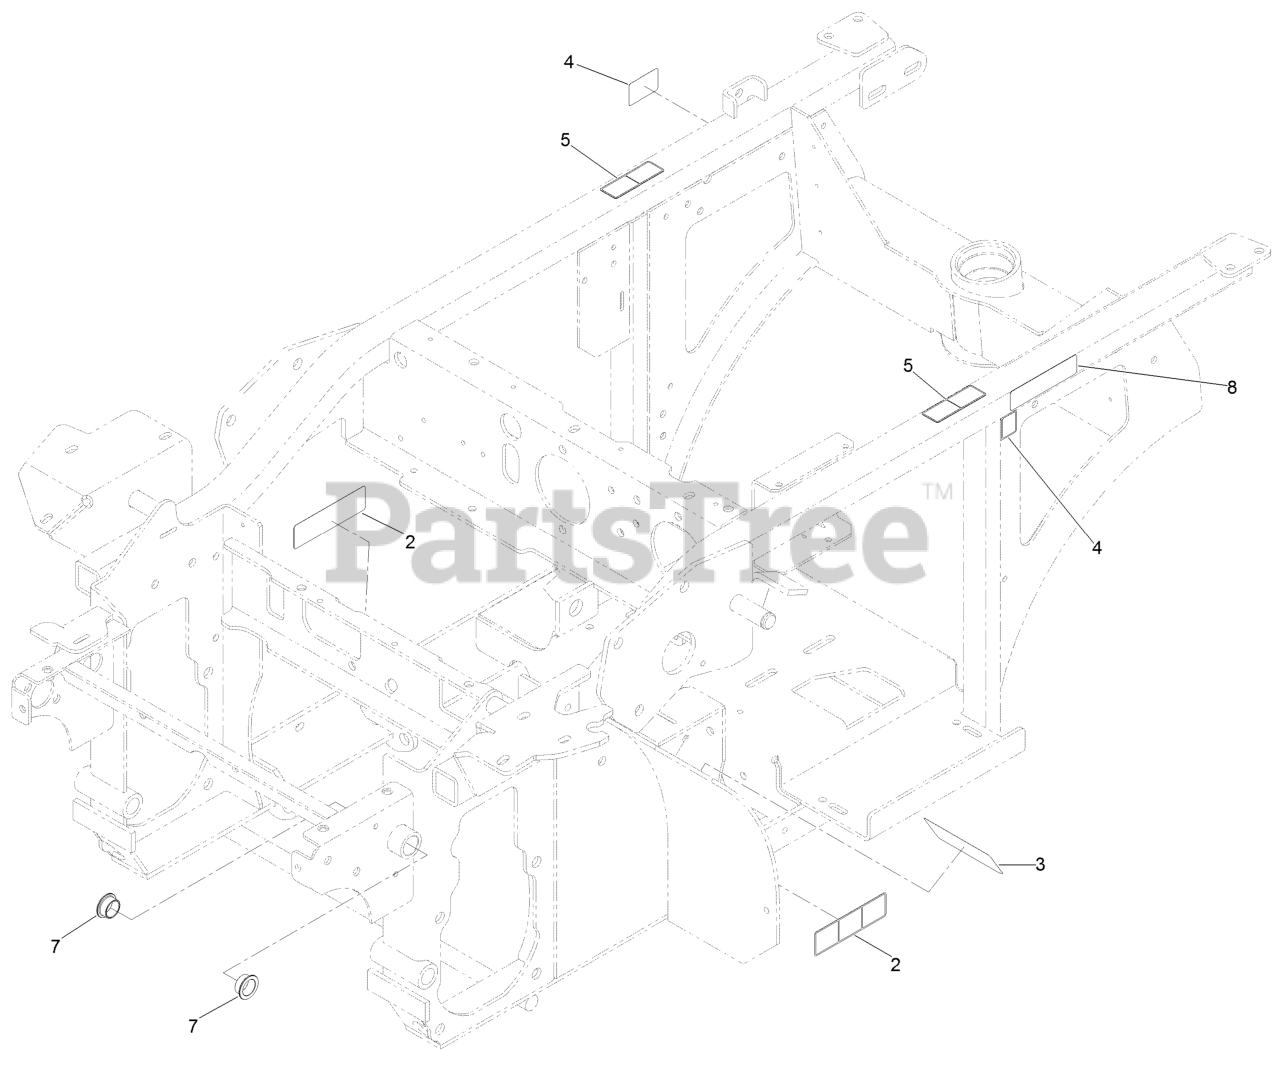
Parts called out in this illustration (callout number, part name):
2	DECAL-COVER, MISSING
3	Decal-Adjustment, Clutch
4	DECAL-WARNING
5	DECAL-WARNING, PINCH POIN
7	BUSHING-BRONZE
8	DECAL-ARRESTER, SPARK
